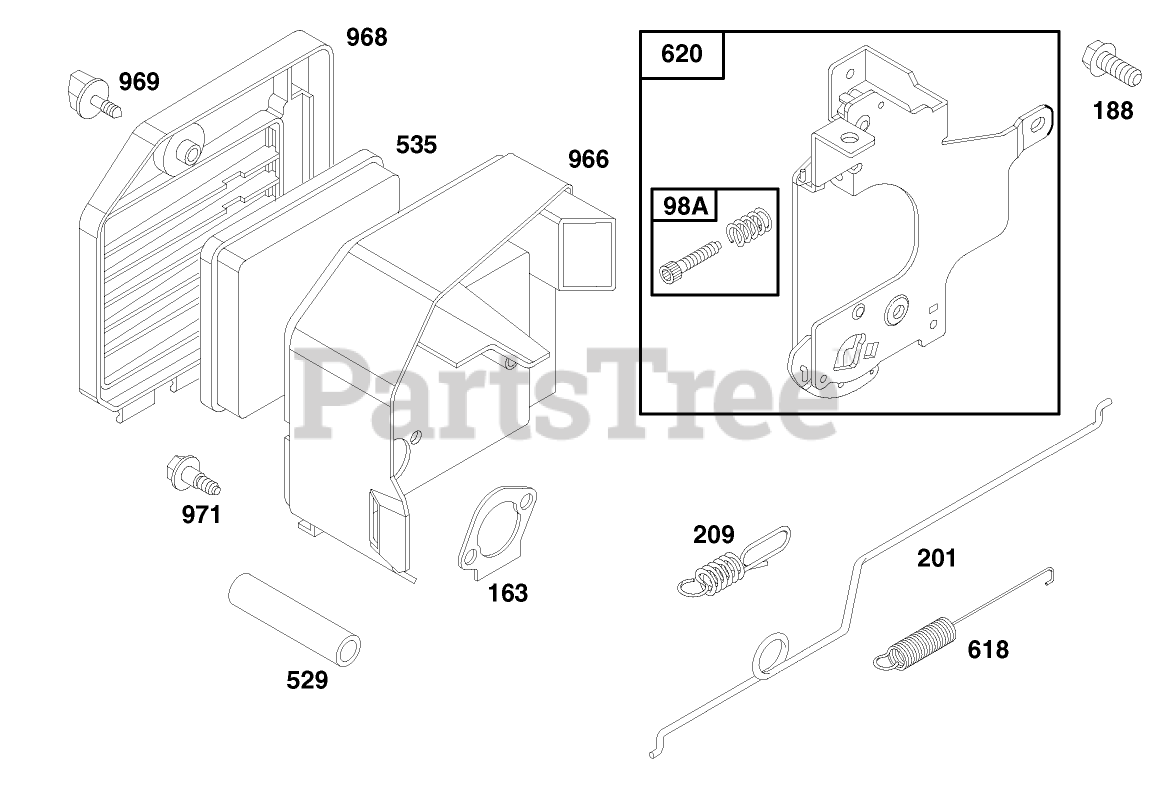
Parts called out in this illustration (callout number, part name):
98A	SPEED ADJUST. SCREW ASM
163	AIR CLEANER GASKET
201	GOVERNOR LINK
209	GOVERNOR SPRING
529	BREATHER TUBE
535	FILTER ELEMENT
618	RETURN SPRING
966	AIR CLEANER BASE
969	AIR CLEANER SCREW
971	AIR CLEANER SCREW
